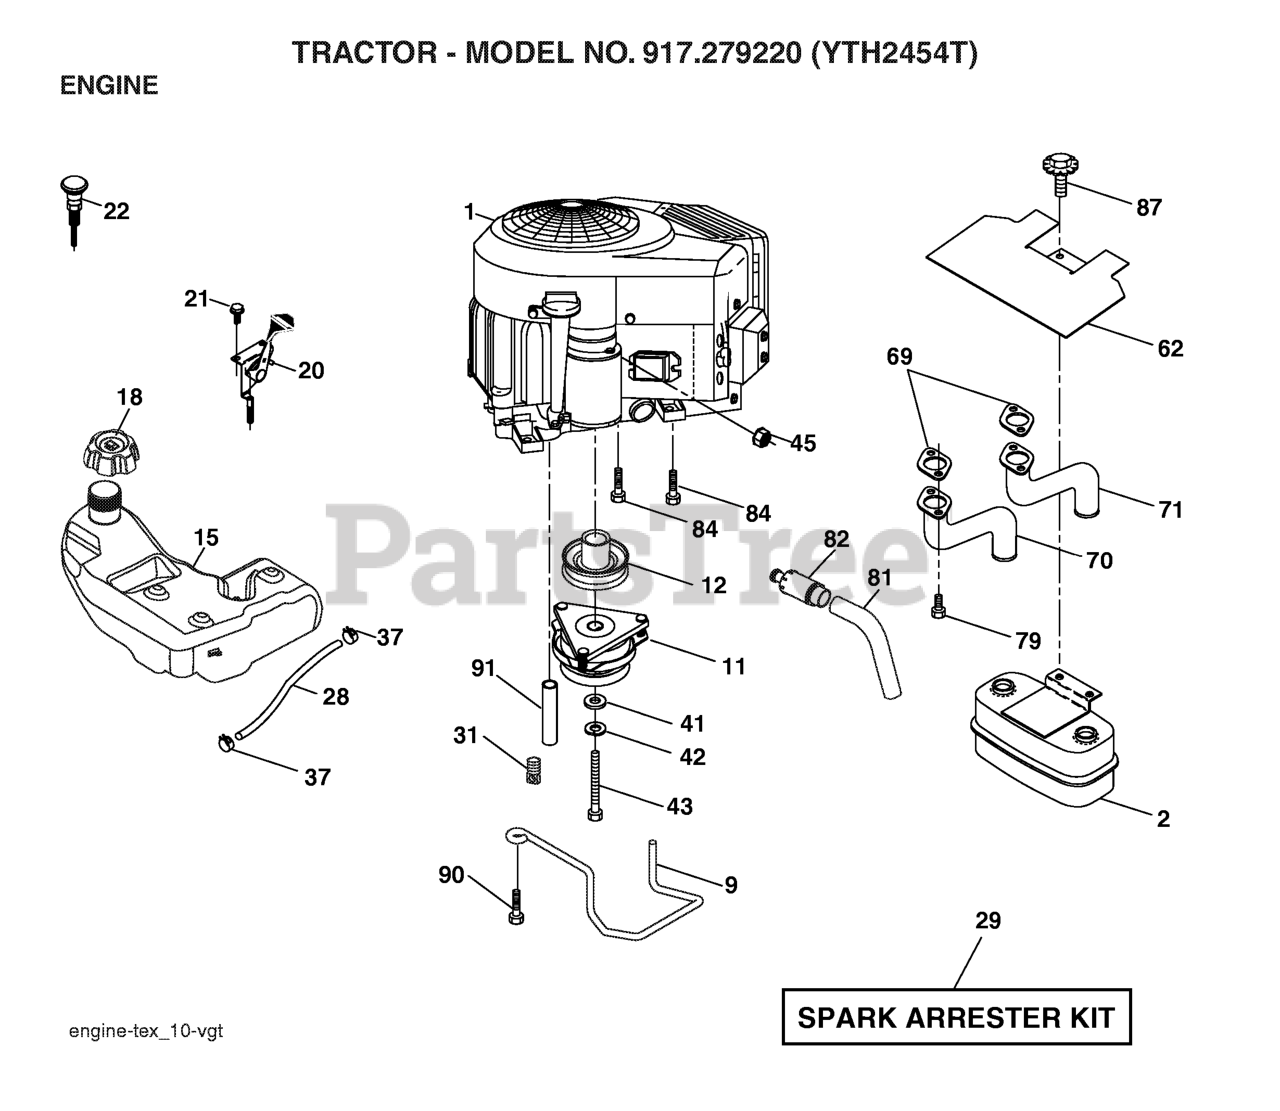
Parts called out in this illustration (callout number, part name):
2	MUFFLER.TWIN.CYL.LOW.TONE
9	KEEPER.BELT.ENGINE.3.25 (3 2)
11	CLUTCH ELECTRIC
12	PULLEY.ENGINE.ENX
15	TANK.FUEL.4GAL
18	CAP.FUEL.TANK.3"GREY
20	THROTTLE CABLE
21	SCREW
22	CONTROL.CHOKE.ERGO.PUSH-IN.BLA
28	LINE.FUEL.64"REAR.EMIS
29	KIT.SPARK ARRESTOR 794945 B&S
37	HOSE CLAMP
42	LOCKWASHER
43	BOLT HEX
45	NUT
62	RP SHIELD HEAT MUFFLER
69	GASKET.MUFFLER
70	RP.EXHAUST.TUBE.LH.BS/TWIN
71	EXHAUST.TUBE.RH.BS/TWIN
79	SCREW.SOCKET.HEAD.5/16-18
81	TUBE, DRAIN OIL ASM.
82	PLUG DRAIN OIL EASY
84	SCREW 3/8-16 X 1-1/2
87	BOLT.5/16-18UNCX1.W/SEMS.BLK
90	SCREW 3/8-16X1
91	BUSHING.1.375OD
